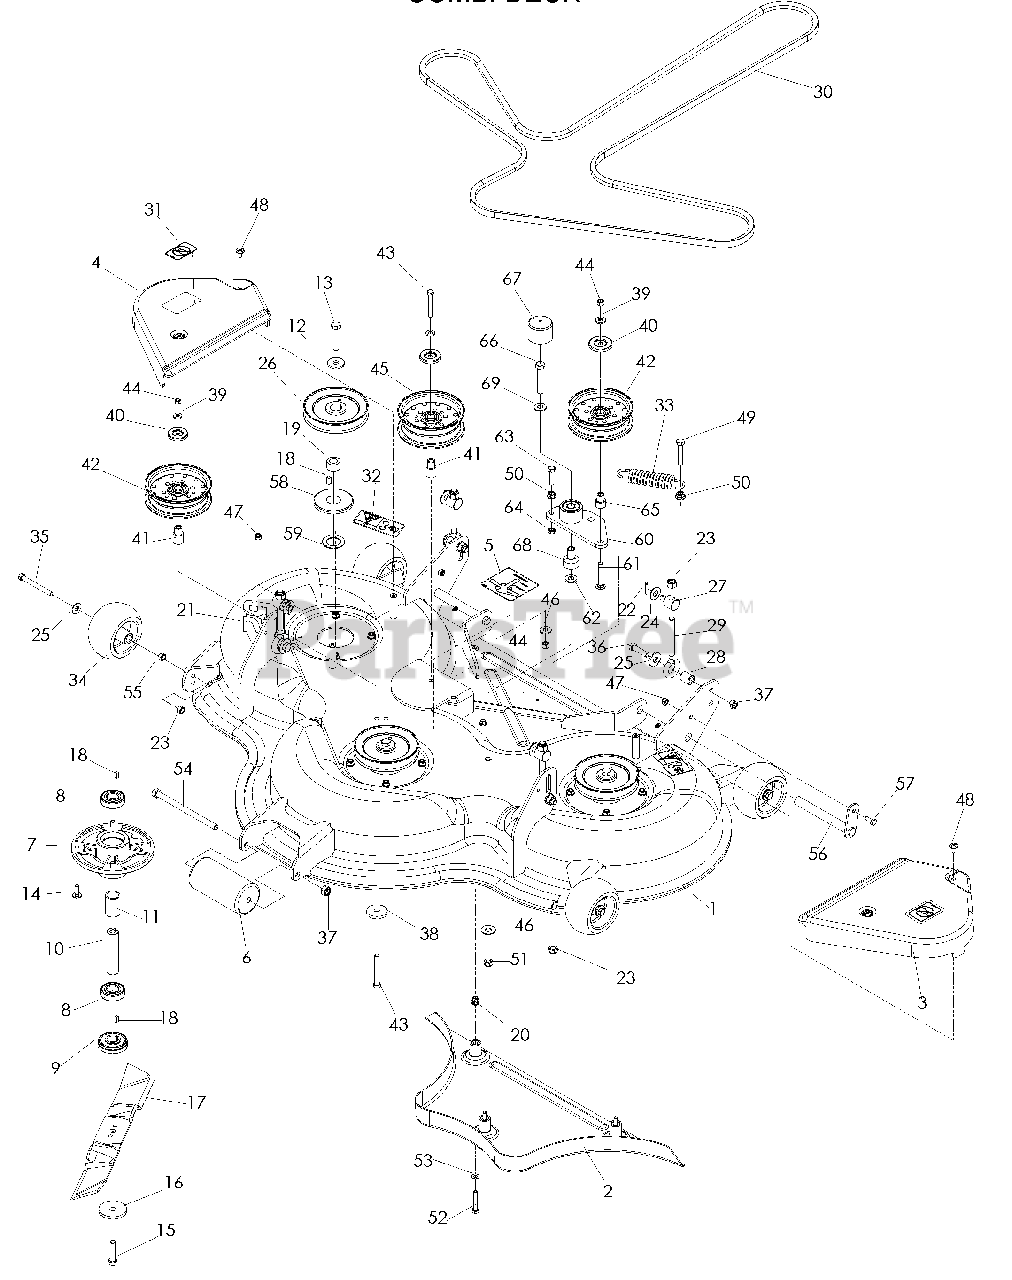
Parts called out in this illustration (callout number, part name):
1	Combi 52" Deck W/Decals
2	Mulch Plug, 132
3	Belt Shield, Lt
4	Belt Shield, Rt
5	Decal, Belt Routing
6	Roller
7	Housing, Bearing
9	Bushing, Blade
12	Washer 1/2
13	Hcs M12 x 1.75 x 60, Gr8.8
14	Rhsnb 5/16-18 x 1
15	Hcs M12 x 1.75 x 50, Gr8.8
17	Blade, C132
19	Key Retainer
20	Blind Rivet Nut
22	Pin Cotter, 1/8 x 1
23	Nut 1/2-13 Hex Nyloc
24	Washer 1/2
25	Washer 1/2
26	Pulley, 52
30	Deck Belt, 52"
31	Decal, No Step
32	Decal, Belt Drives
34	Wheel, Gauge
35	Hcs 1/2-13 x 4
36	Hcs 7/16-14 x 1 3/4
37	Nut 7/16-14, Ctrlk, Gr A
38	Washer, Heavy
39	Washer 3/8, Thick
40	Shield, Dust
41	Bushing, Idler
42	Pulley, Idler
43	Hcs 3/8-16 x 2 3/4
44	Nut 3/8-16 Hex Nyloc
45	Pulley, Idler (Tall)
46	Washer 3/8
47	Nut 5/16-18 Flange Nyloc
48	Screw 1/4-20 x 5/8, Self Tap
49	Hcs 3/8-16 x 2
50	Nut 3/8-16, Whizlk
51	Nut, 3/8-16 Hex Jam Nyloc
52	Hcs M8 x 1.25 x 50, Gr8.8
53	Washer 5/16, Sae
54	Hcs 7/16-14 x 7
55	Nut 1/2-13
56	Pin, Strut
57	Hcs 5/16-18 x 1
58	Dust Cap, Bottom
59	Washer 1.06
60	Arm, Idler W/Bearings
61	Bolt 3/8-16 x 2 1/2, Carriage
62	Washer 1/2, Sae
63	Hcs 3/8-16 x 1 1/2 Gr8
64	Nut 3/8-16 Jam
65	Bushing, Idler
66	Hcs 1/2-13 x 2 3/4
67	Cap, Vinyl
68	Pivot, Bearing
69	Washer 1/2, Belleville
